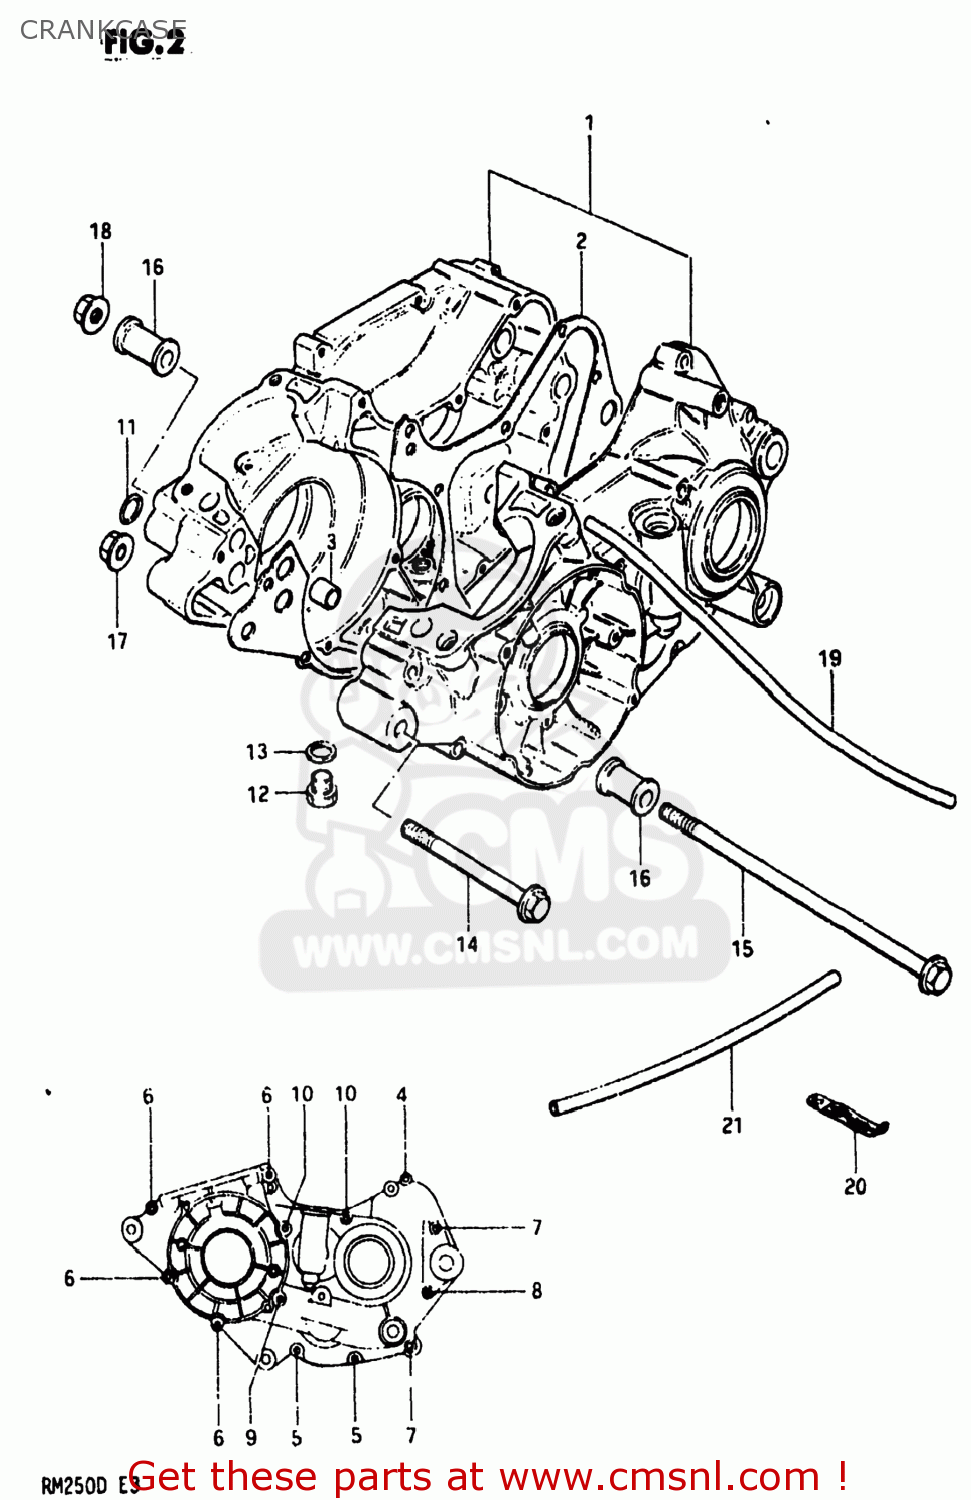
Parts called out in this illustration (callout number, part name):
1	CRANKCASE SET
2	GASKET,CRANKCASE (MCA)
3	PIN
4	SCREW 6X30
5	SCREW (6X35)
6	SCREW (6X45)
7	SCREW
8	SCREW
9	SCREW 6X60
10	SCREW 6X70
11	O RING(D:1.9,ID:13.8)
12	PLUG
13	GASKET(14X19.2X2) (NAS)
14	BOLT(8X100)
15	BOLT 8X220
16	SPACER,ENGINE MOUNT
17	NUT
18	NUT
19	HOSE
20	CLAMP
21	HOSE
